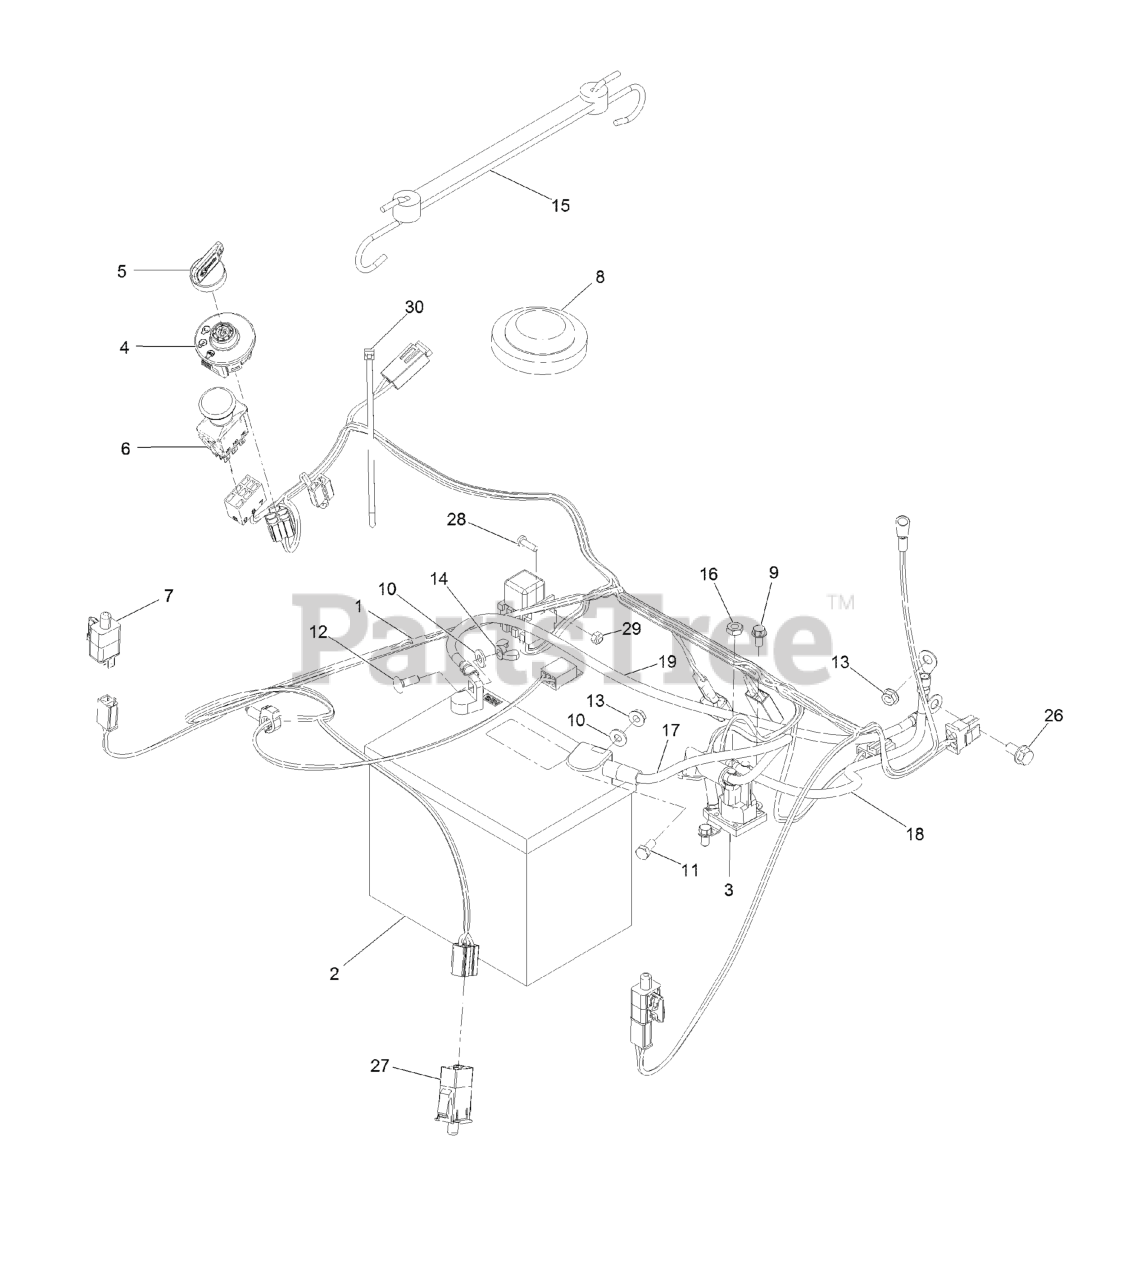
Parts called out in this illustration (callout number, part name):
1	HARNESS-WIRE
2	BATTERY
3	SOLENOID
4	SWITCH-IGNITION
5	KEY-IGNITION
6	SWITCH-PTO
8	SWITCH-SEAT
9	SCREW-HWH
10	WASHER-FLAT
11	SCREW-HH
12	BOLT-CARR
14	NUT-WING
15	HOLDDOWN-BATTERY
16	NUT-JAM
17	CABLE-BATTERY, RED
18	CABLE-BATTERY, RED
19	CABLE-BATTERY, BLACK
26	SCREW-HHF
27	SWITCH-DELTA
28	SCREW-PPH
29	NUT-LOCK, NI
30	TIE-CABLE
